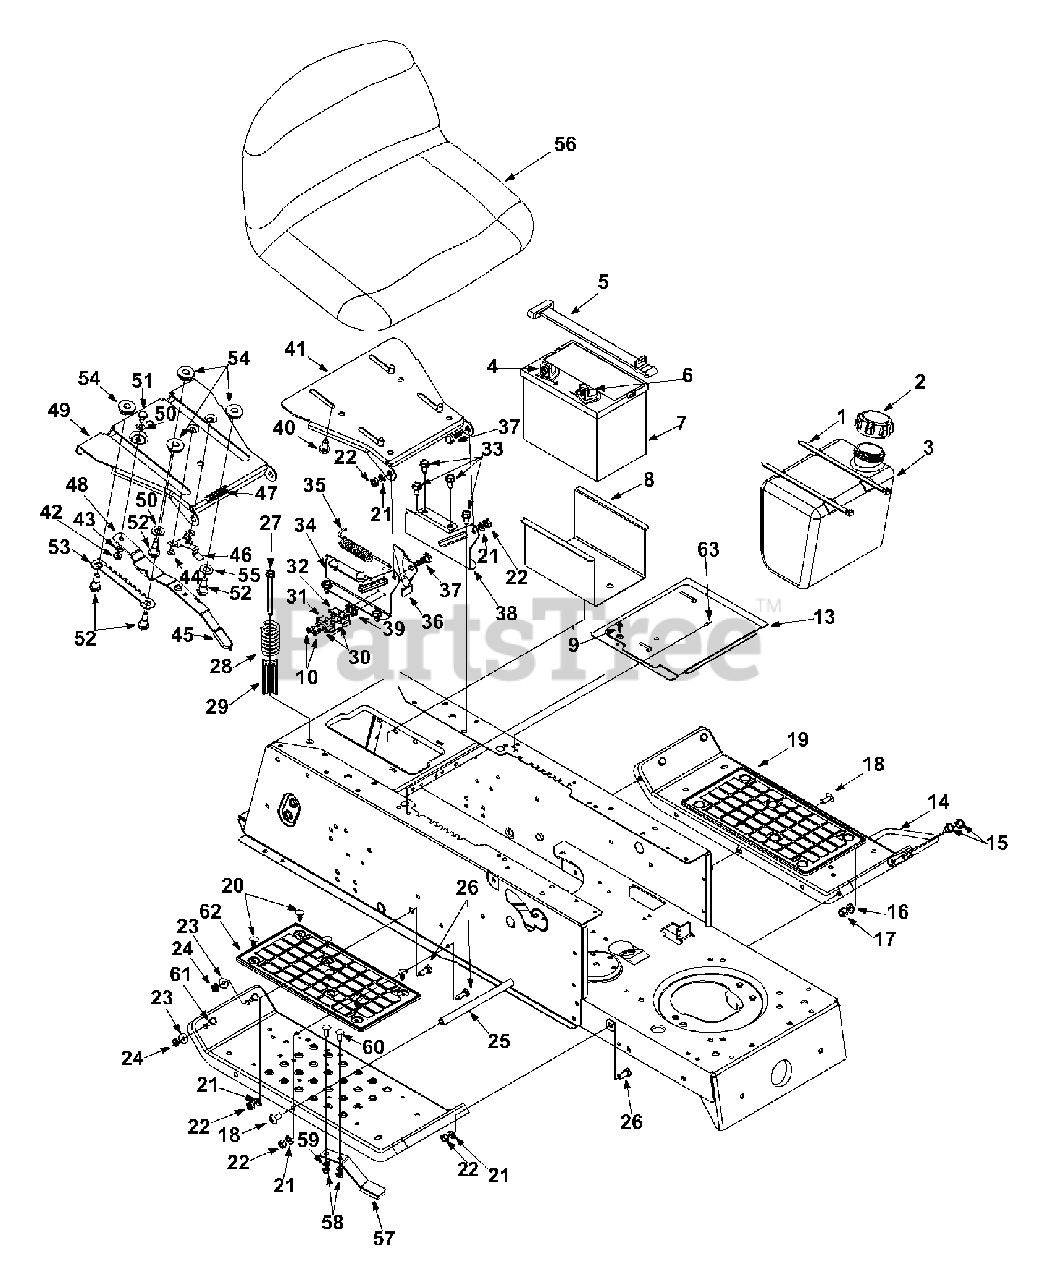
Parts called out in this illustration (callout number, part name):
1	Cable Tie
2	Fuel Cap
3	Fuel Tank 1.25 Gal.
4	Sems Hex Nut 1/4-20 Thd.
5	Battery Strap
6	Hex Hd. Cap Screw 1/4-20 Gr. 5
7	Battery
9	Truss Mach. B-Tap Scr. #10 x .5" Lg.
10	Hex AB-Tap Scr. #8 x .50" Lg.
15	TT-Tap Scr. 5/16-18 x .625" Lg.
16	L-Wash. 3/8
17	Hex Nut 3/8-16 Thd. Gr. 8
18	Truss Mach. Scr. 5/16-18 x .75"
21	L-Wash. 5/16" I.D.
22	Hex Nut 5/16-18 Thd.
23	Bell-Wash. .265" I.D. x .75" O.D.
24	Hex Nut 1/4-20
25	Running Board Rod
26	Hex Bolt 5/16-18 x .75" Lg.
27	Hex Tap Scr. 5/16-18 x 3.25" Lg.
28	Compression Spring
29	Spring Spacer
30	Insulator Plate
31	Outer Spring Switch Spring
32	Inner Spring Switch Spring
33	Hex Wash. AB Scr. 5/16-12 x .75"
35	Extension Spring
36	Seat Lift Brkt.
37	Shoulder Bolt .437" Dia. x .268"
39	Insulator Boss Plate
40	Hex Tap Scr. 3/8-16 x .62" Lg.
42	Hex Flanged L-Nut 1/4-20 Thd.
43	Spring Wash. .265 I.D. x .562 O.D.
45	Seat Adj. Grip
46	Seat Adj. Stop
47	Compression Spring
48	Seat Adj. Lever
51	Shoulder Bolt .34" x 1/4-20 Thd.
52	Shoulder Scr. 3/8-16
53	Seat Adj. Selector
54	Seat Adj. Spacer
55	Fl-Wash. .344 I.D. x .62 O.D.
56	Low Back Black Seat
57	Blade Brake Assembly
58	Hex Nut 1/4-20 Thd.
59	L-Wash. 1/4" I.D.
60	Carriage Bolt 1/4-20 x .62" Lg.
61	Hex Hd. Cap Scr. 1/4-20 x .62" Lg.
62	Rubber Foot Pad
63	Snap Bushing
